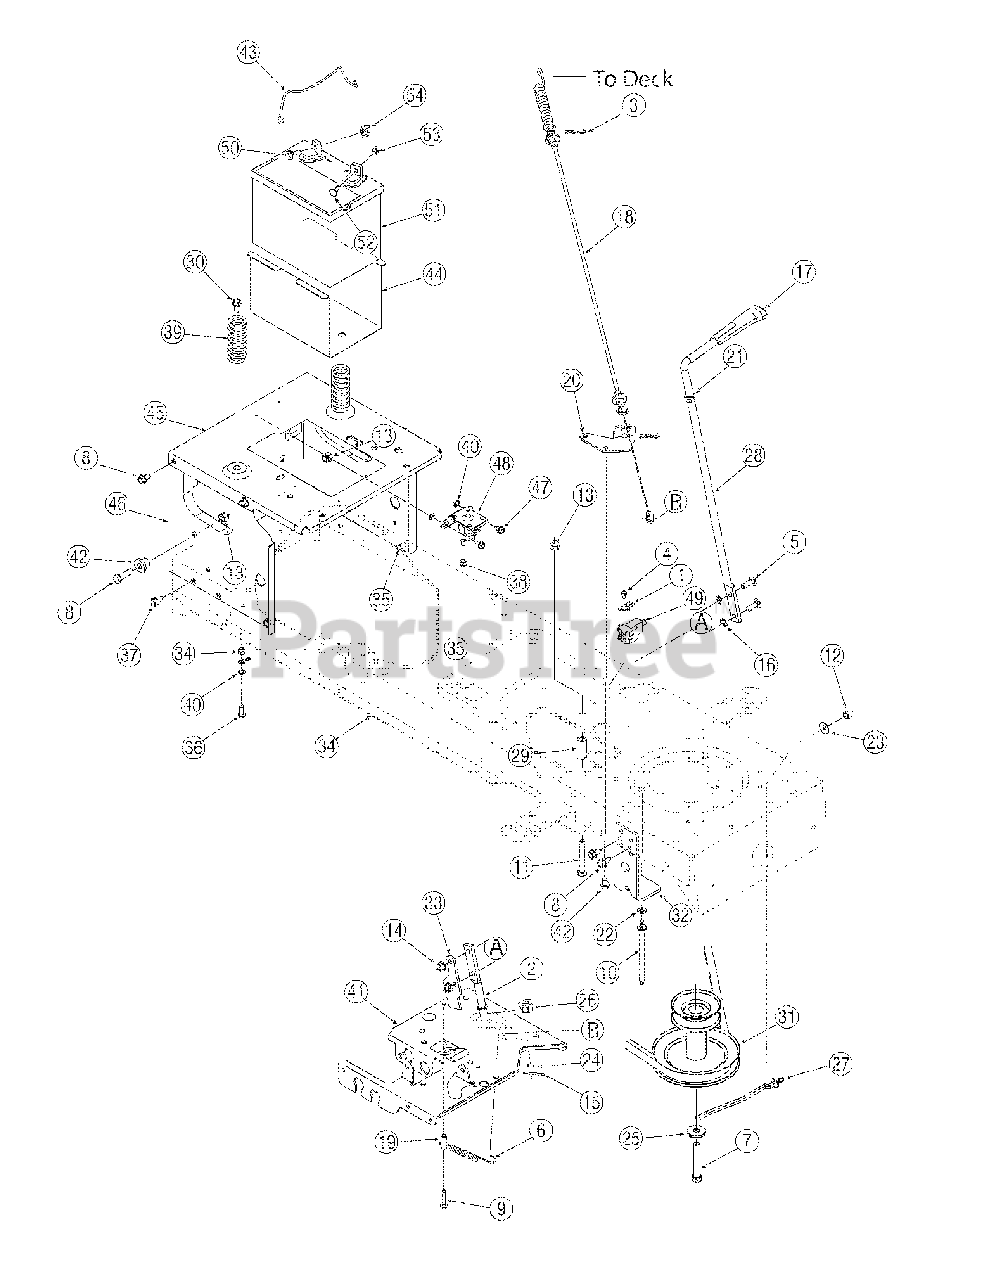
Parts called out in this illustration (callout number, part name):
1	Plate, Switch
2	Lever Assembly, Engagement
3	Click Pin
4	Screw, #10-16, 0.500
5	Screw, Carriage, 5/16-18, 1.00
6	Extension Spring, .38 OD x 3.9 LG
7	Screw, 7/16-20, 2.75, Gr5
8	Screw, 5/16-12, 0.750
9	Screw, 1/4-20 x 1.50
10	Pin, Belt Guard, 5/16 x 4.75
11	Screw, 3/8-16 x 2.50
12	Nut, Flange Lock, 5/16-18, GrF
13	Nut, Flange Lock, 3/8-16, GrF
14	Nut, Flange Lock, 5/16-18, Gr5
15	Pin, Cotter, 1/8 x 1.25
16	Nut, Speed, .3125 ID
17	Knob, PTO
18	Deck Engagement Cable
19	Spacer, .260 x .372 x 1.030 Lg.
22	Washer, Lock, 5/16
23	Washer, Bell, .340 x .872 x .060
24	Washer, Flat, .344 x .688 x .065
25	Washer, Flat, .450 x1.250 x.164
26	Bearing, Flange, Hex Split .500 ID
27	Keeper Rod, Belt
28	Engagement Handle, Deck
29	Spacer, .385 ID x .635 OD x 1.54
30	Screw, 5/16-18 x .750
31	Pulley, Engine, 3.39 x 6.12 Dia
34	Frame Assembly, Lower
35	Screw, 5/16-18, 0.500
36	Screw, 1/4-20, 0.750
37	Screw, 3/8-16, 1.25, Gr5
38	Nut, Flange Lock, 1/4-20, GrF
39	Spring, Compr., 1.28 OD x 3.125
40	Washer, Lock, 1/4, External
41	Support Bracket, Steering
42	Spacer, Shoulder, .38 x 1.0 x .70
43	Hold Rod, Battery
48	Solenoid, 12V, 100 Amp
49	Switch, Interlock
50	Screw, Shoulder, .250 x .150
51	Battery, 190 CCA
52	Screw, Carriage, 1/4-20, .75, Gr5
53	Nut, Sems, 1/4-20
54	Nut, Wing, 1/4-20
